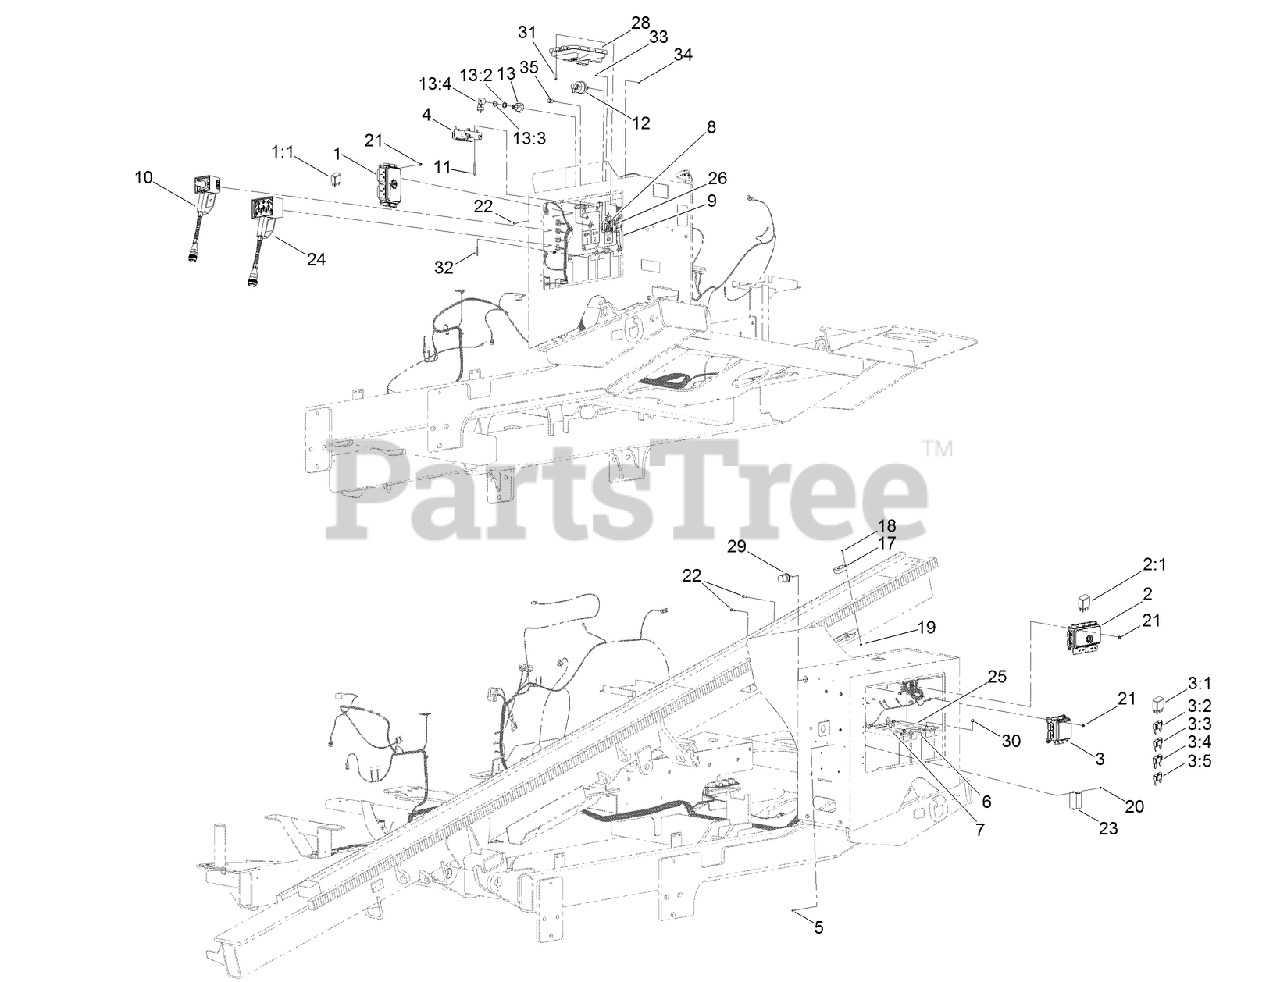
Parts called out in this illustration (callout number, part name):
1	BOX-VEC, MAIN (A)
1:1	RELAY-280 ISO
2	BOX-VEC, MAIN (B)
2:1	RELAY-280 ISO
3	BOX-VEC, MAIN (C)
3:1	RELAY-280 ISO
3:2	FUSE-MINI BLADE, 2 AMP
3:3	FUSE-MINI BLADE, 5 AMP
3:4	FUSE-MINI BLADE, 20 AMP
3:5	FUSE-MINI BLADE, 30 AMP
4	COMPUTER-EXPANDER, OUTPUT
5	SCREW-PPH
6	CABLE-BATTERY, POSITIVE
7	CABLE-BATTERY, NEGATIVE
8	CABLE-BATTERY, POSITIVE
9	CABLE-BATTERY, POSITIVE
10	TRAVEL PENDANT ASM
11	SCREW-FLANGE, METRIC
12	SWITCH-DISCONNECT, MASTER
13	IGNITION SWITCH ASM
13:2	NUT-HEX
13:3	NUT-FACE
13:4	IGNITION KEY SET
17	SWITCH-PROXIMITY
18	SCREW-PPH
19	NUT-KEPS
20	NUT-LOCK
21	NUT-FLANGE, NI
22	SCREW-HHF
23	CONNECTOR-PACK, RESISTOR
24	LIFE JACKET ASM
25	Battery
26	HARNESS-WIRE, FUSIBLE LINK
28	CONTROLLER ASM (88 PIN, UNPROGRAMMED)
29	POST-BATTERY, REMOTE
30	NUT-KEPS
31	SCREW-HHF
32	RIVET-POP
33	SCREW-PRH, SLOTTED
34	NUT-LOCK, NI
35	LAMP-INDICATOR, LED
